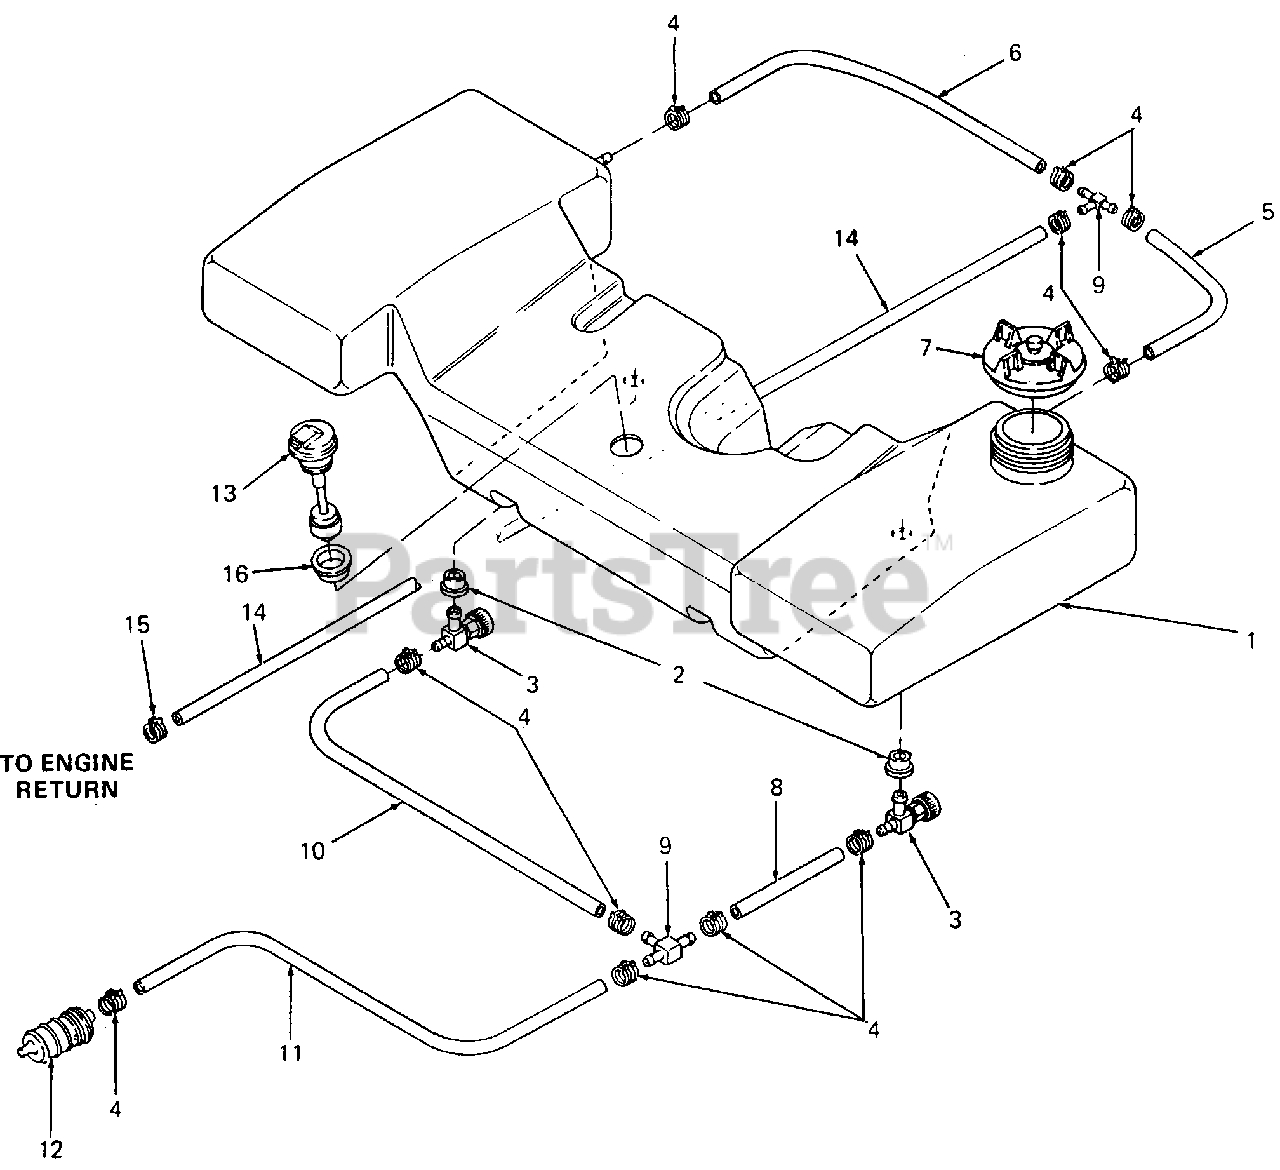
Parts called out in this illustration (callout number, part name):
1	Tank, Fuel
2	Bushing
3	Valve, Fuel Shutoff
4	Clamp, Hose
5	Line, Fuel -9" Lg
6	Line, Fuel -14" Lg
7	Cap, Fuel
8	Line, Fuel -5" Lg
9	T-Fitting
10	Line, Fuel -19" Lg
11	Line, Fuel -38" Lg
12	Filter, Fuel
13	Sensor, Low Fuel
14	Line, Fuel -73" Lg
15	Clamp, Hose
16	Bushing, Rubber
